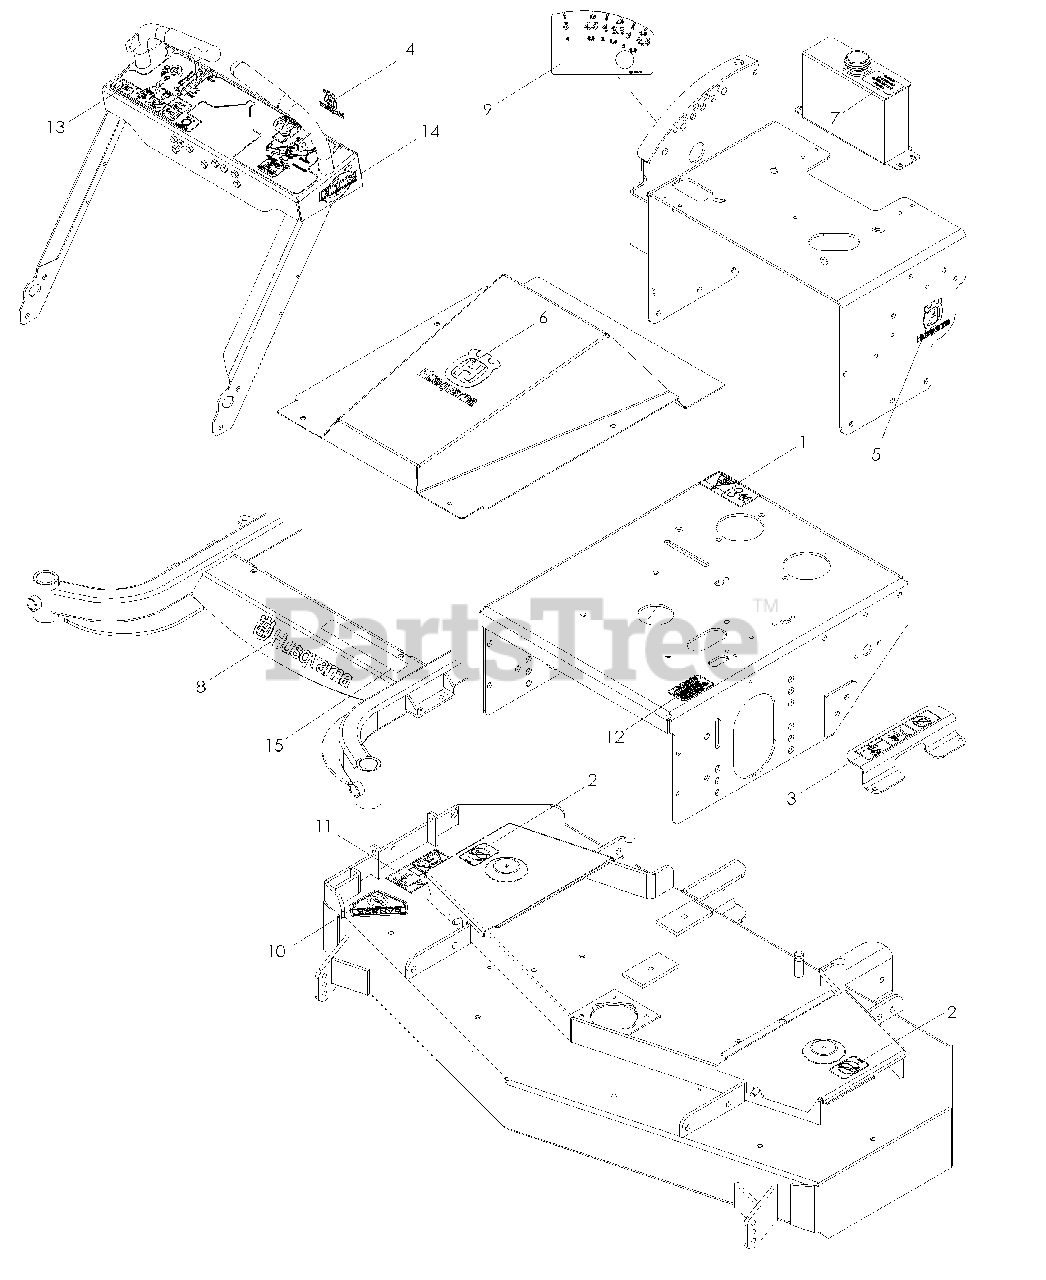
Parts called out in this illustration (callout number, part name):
1	DECAL, BELT DRIVES
2	DECAL, NO STEP
3	DECAL, BATTERY WARNING
4	DECAL, CROWN 21/4"
5	DECAL, CROWN 31/8"
6	DECAL, CROWN 51/4"
7	DECAL, OIL TANK
8	DECAL, HUSQ 91/4"
9	DECAL, CUT HEIGHT
10	DECAL, CPSC
11	DECAL, SEVERING
12	DECAL, PROP 65
13	DECAL, CONSOLE
14	DECAL, ETS
15	DECAL, WHF4817
15	DECAL, WHF5219
15	DECAL, WH5221
